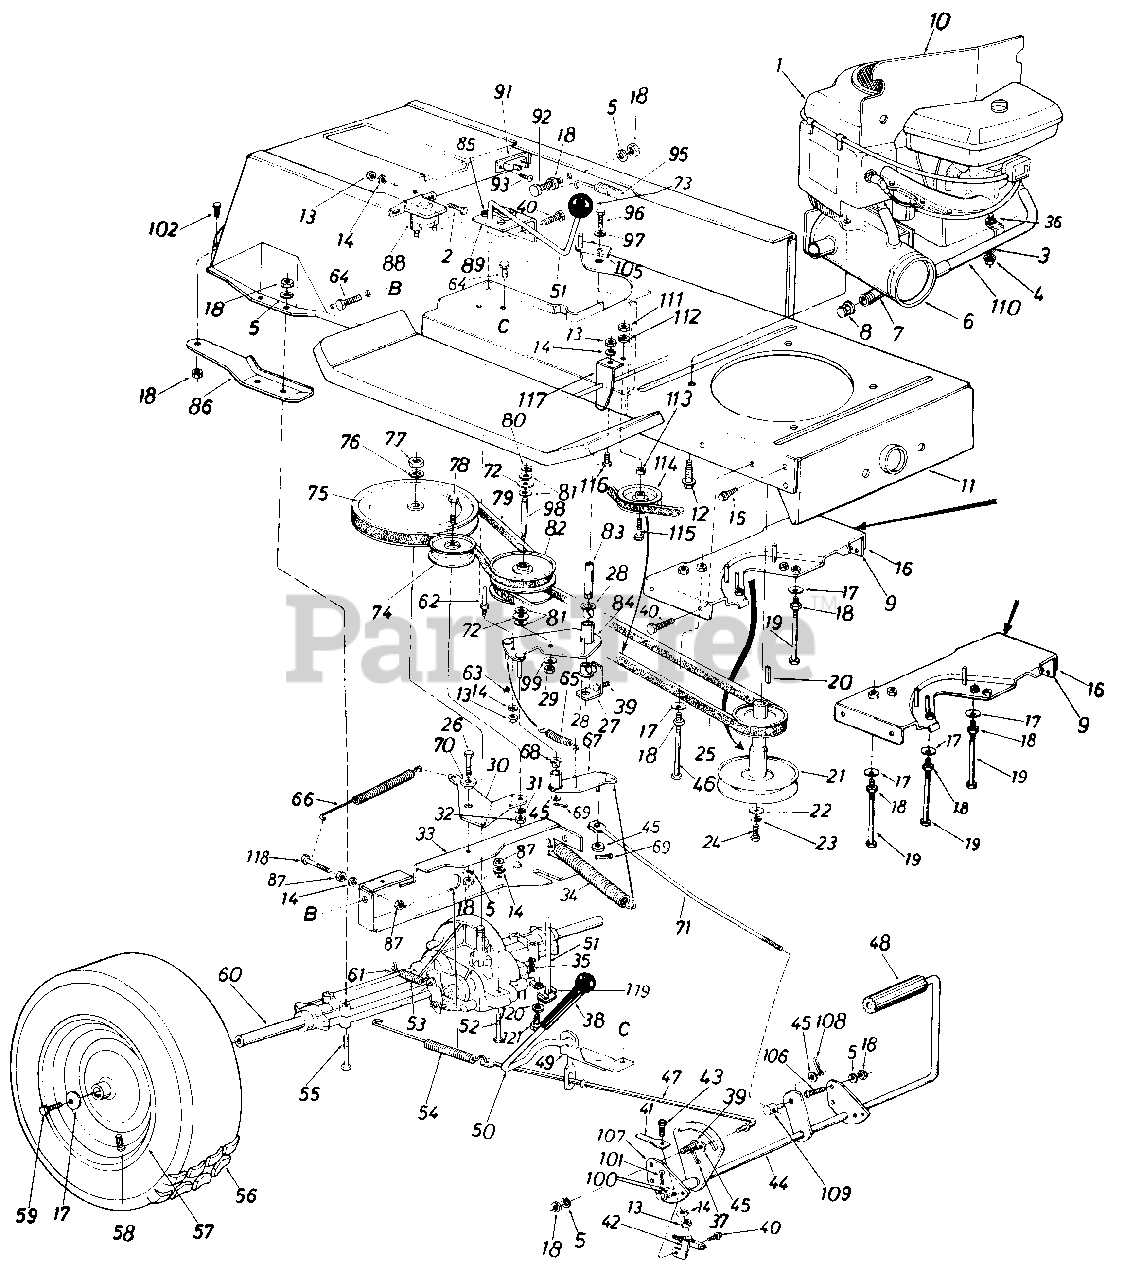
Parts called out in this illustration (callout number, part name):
1	Engine
2	Hex Bolt 1/4-20 x .62" Lg.
3	Special L-Wash. 5/16" I.D.
4	Hex Nut 5/16-18 Thd.
5	L-Wash. 5/16" I.D.
6	Exhaust Muffler
7	Pipe Nipple
8	Cap Oil Drain
9	Brake Cable Brk't.
10	Heat Shield
11	Lower Frame Ass'y.
12	Hex Wash. Hd. TT-Tap Scr. 3/8-16 x 1.25" Lg.
13	Hex Nut 1/4-20 Thd.
14	L-Wash. 1/4" I.D.
15	Hex Wash. Hd. AB-Tap Scr. 5/16" x.75" Lg.
16	Belt Guard Brkt. Ass'y.
17	Bell-Wash. .345" I.D. x .88"
18	Hex Nut 5/16-18 Thd.
19	Hex Bolt 5/16-18 x 4.00"
20	Sq . Key 1/4 x 1/4 x 2.00"
21	Engine Pulley
22	Fl-Wash. 7/16" I.D. x 1.25"
23	L-Wash. 7/16" I.D.
24	Hex Bolt 7/16-20 x 1.50" Lg.
25	Variable-Speed Belt .715 x 53" Lg.
26	Hex Bolt 5/16-18 x .75" Lg.
27	Bearing Shaft Bracket Ass'y.
28	Flanged Nyliner Brg. 5/8" I.D. x .88" Lg.
29	Hex Nut 3/8-24 Thd.*
30	Idler Bracket
31	L-Wash. 3/8" I.D.
32	Hex Nut 3/8-24 Thd.
33	Transaxle Support Brkt.
34	Ext. Spring .94" O.D. x 6.7
35	Inter. Cotter Pin
36	Fl-Wash. .34" I.D. x .62" O.D. x .033
37	Cotter Pin 3/32" Dia. x .75"
38	Grip-Black
39	Truss Mach. Scr. 5/16-18 x .75" Lg.
40	Hex Wash. Hd. Self-Tap Scr. 1/4-20 x .50" Lg.
41	Switch Actuator
42	Safety Switch
43	Hex Bolt 1/4-20 x 1.0" Lg.
44	Clutch & Brake Pedal Ass'y.
45	Fl-Wash.
46	Hex Bolt 5/16-18 x 4.5"*
47	Brake Rod 20.9" Lg.
48	Foot Pad
49	Brake Lever Bracket
50	Hill Holder Brake Handle
51	Shift Lever Ass'y.
52	Hex Bolt 1/4-28 x 1.75" Lg.
53	Ext. Spring .38" O.D. x 2.5"
54	Ext. Spring .59" O.D. x 7.08"
55	Hex Bolt 5/16-18 x 2.75"
57	Wheel Rim Only
58	Air Valve
59	Hex Bolt 5/16-24 x .75" Lg.
60	Transaxle Complete-R.H.
61	Brake Return Spring Anchor
62	Belt Guard Pin 1/4-20 Thd.
63	Cap Speed Nut 1/4" Dia.
64	Hex Wash. TT-Tap Scr. 5/16 x .62" Lg.
65	Ext. Spring .50" Dia.
66	Ext. Spring .62" O.D. x 6.12"
67	Variable Speed Torque Brkt. Ass'y.
68	Flanged Bearing
69	Cotter Pin 3132" Dia.
70	Shoulder Spacer .500" Dia. x.27" Lg.
71	Speed Control Link
72	Truss Bearing .56 Dia. x 1 .25"
73	Ball Knob
74	Fl-Idler Pulley 3.25" x 1.0"
75	1/2" "V"-Pulley 8.0" O.D. x .501 " I.D.
76	L-Wash. 1/2" I.D.
77	Hex Jam Nut 1/2-20 Thd.
78	Hex Bolt 3/8-24 x .75" Lg.
79	Variable Speed Belt .715 x 44" Lg.
80	Snap Ring .56" Dia.
81	Fl-Wash.
82	Variable Speed Pulley Ass'y. 5" O.D.
83	Bearing Shaft
84	Variable Speed Brkt. Ass'y.
85	Comp. Spring Clip
86	Transaxle Support Brkt.-R.H.
87	Hex Nut 1/4-28 Thd.
88	Solenoid
89	Shift Lever Bracket
91	Circuit Breaker
92	Hex Bolt 5/16-18 x 1.50" Lg.
93	Truss Hd. Phil. Scr. #10 x 1/2" Lg.
95	Ext. Spring .99" O.D. x 11.0"
96	Hex Bolt 3/8-24 x .75" Lg.
97	Bell-Wash. .38" I.D. x .88"
98	Shaft .56" Dia. x 3.875" Lg.
99	Bell-Wash. .39" I.D. x 1.12"
100	Fl-Wash.
101	Cotter Pin 3/32" Dia. x .75"
102	Hex Wash. Hd. Scr. 5/16-18 x.62" Lg.
105	Belt Guard
106	Hex Bolt 5/16-18 x .75" Lg.
107	Pedal Bracket
108	Cotter Pin 3/32 x .75"
109	Ferrule
110	Inlet Tube Ass'y.
111	Hex Nut 3/8"-16 Thd.
112	L-Wash. 3/8" I.D.
113	Fl-Wash. .390" I.D. x 1.12"
114	Fl-Idler w/Flanges 2.750
115	Hex Bolt 3/8-16 x 2.00" Lg.
116	Hex Bolt 1/4-20 x .62" Lg.
117	Spring Hanger Bracket
118	Hex Bolt 1/4-28 x 1.25" Lg.
119	Shift Lever Link Ass'y.
120	Bell-Wash. .265 I.D. x .75 O.D.
121	Hex Bolt 1/4-28 x .62" Lg.
